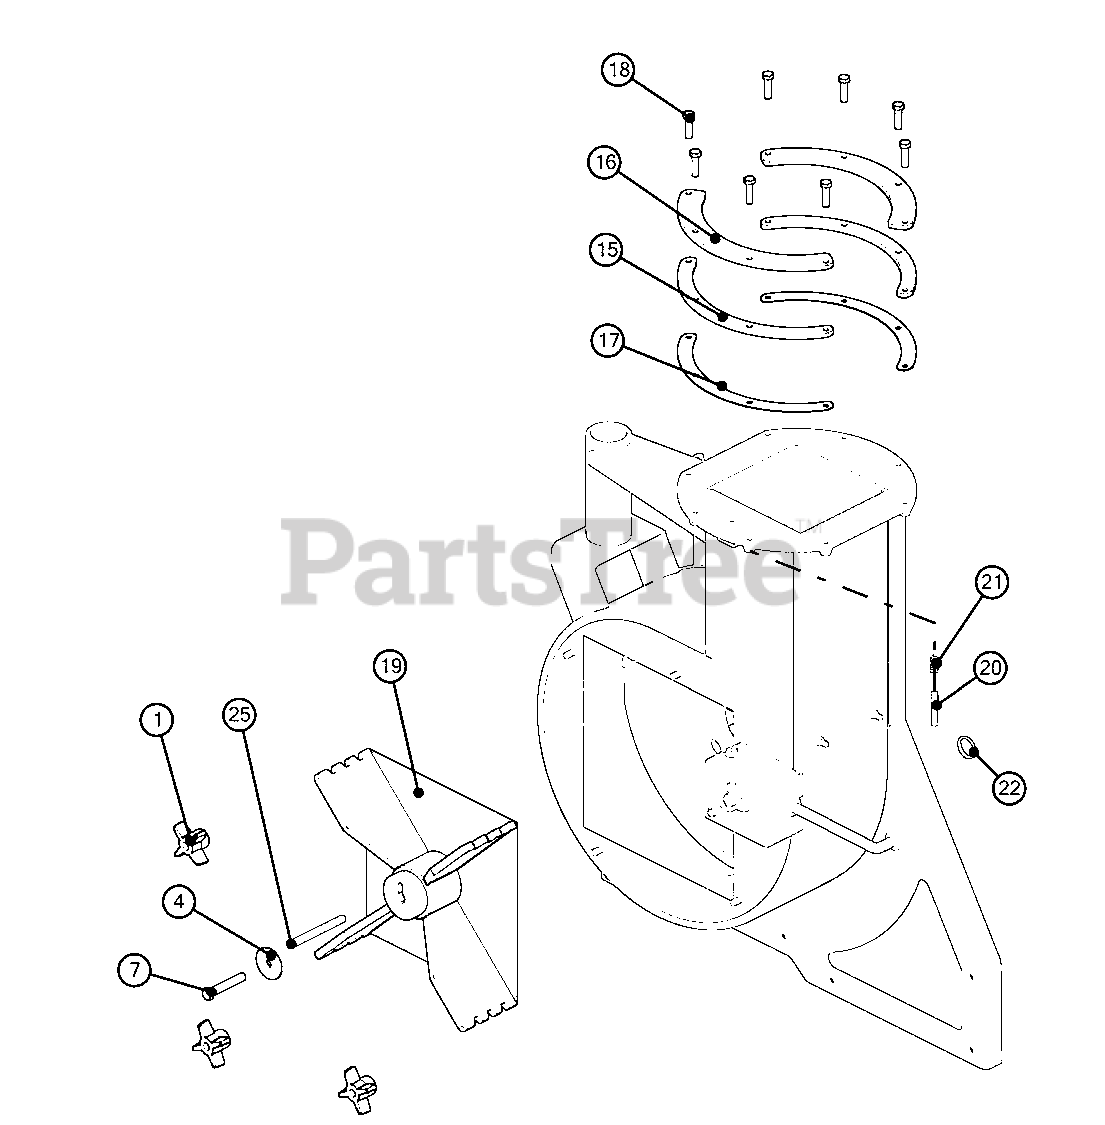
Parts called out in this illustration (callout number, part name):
1	Knob-5/16 THRD
4	Washer, Area VAC 35 - 29/64 x 3/4
7	Bolt, Hex .38-24 x 2.5 GR5 EP80
15	Spacer, Flange
16	Flange, Top
17	Spacer, Flange .060
18	Bolt, Hex .31-18 x 1.25 GR5
19	Fan Weldment 20 TL
20	Pin, Spring Latch
21	Spring, Comp. .028 x .34 x 1.062
22	Ring, Locking
25	Key, Square .250 x 4.00
